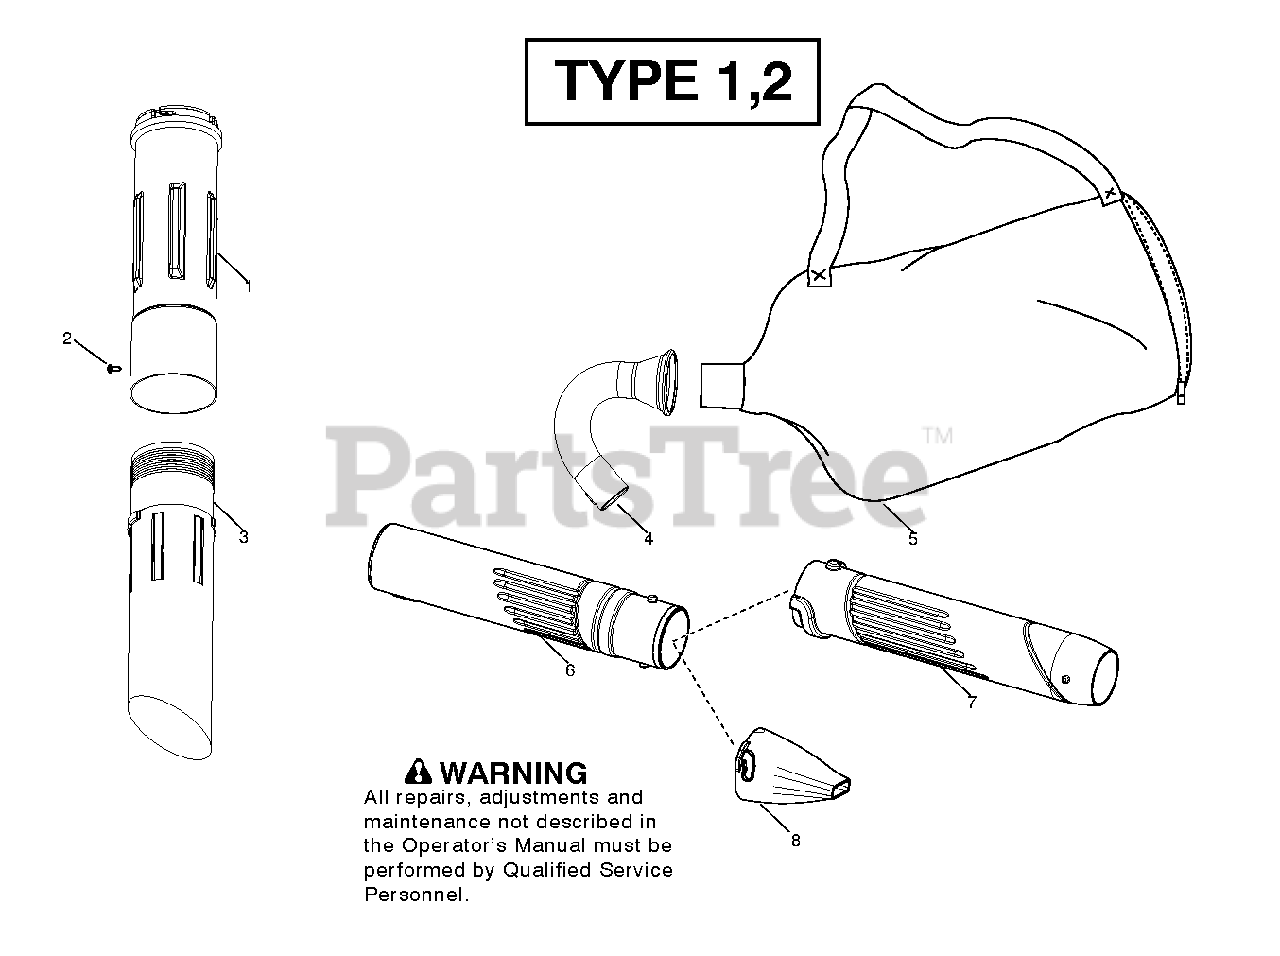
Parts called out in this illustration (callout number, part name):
1	TUBE VAC UPPER BLACK
4	TUBE VACUUM J BLACK
5	ASSY VAC BAG GAS W/STRAP
6	BLOWER TUBE
7	TUBE BLOWER LOW END BLACK
8	NOZZLE BLACK HI SPEED ADAPTOR
